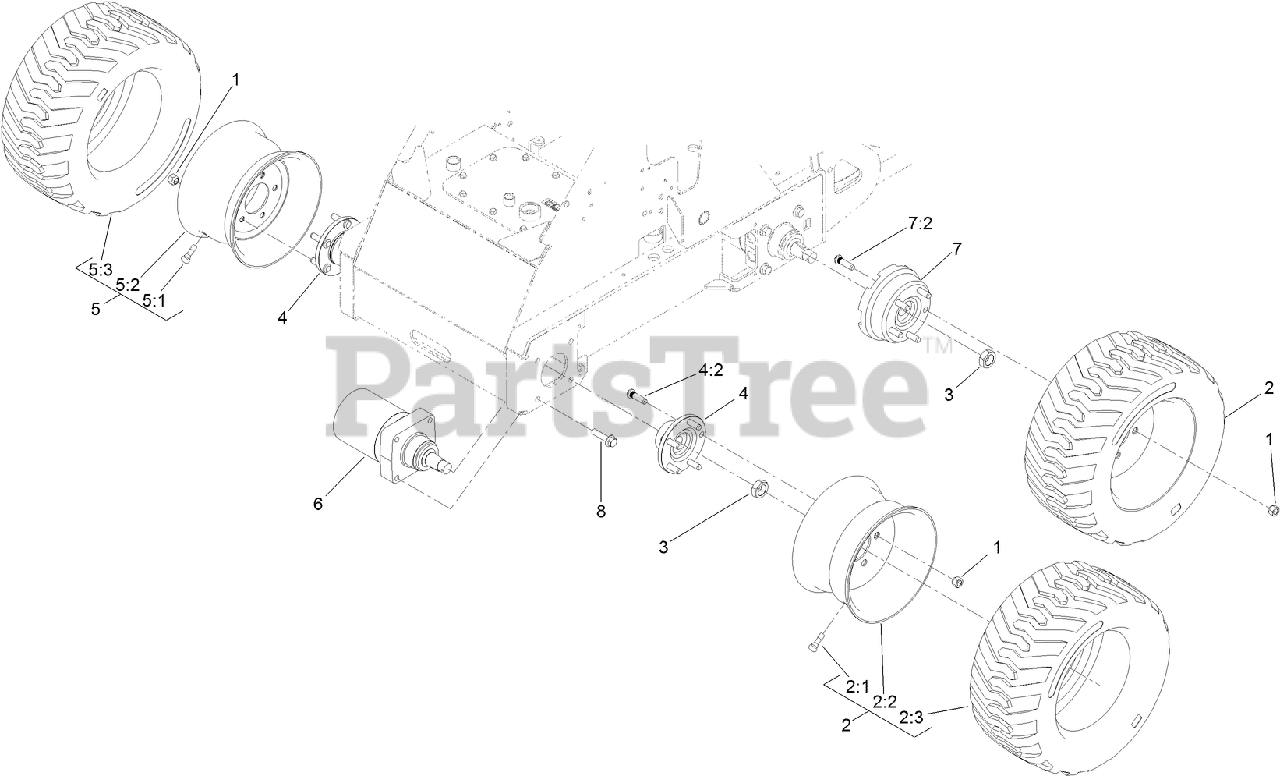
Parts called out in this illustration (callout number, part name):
1	NUT-LUG
2	LH WHEEL AND TIRE ASM
2:2	WHEEL
3	NUT-LOCK
4	HUB ASM
4:2	STUD-TYPE, DRIVE
5	RH WHEEL AND TIRE ASM
5:2	WHEEL
6	HYD MOTOR ASM
7	WHEEL HUB ASM
7:2	STUD-TYPE, DRIVE
8	SCREW-HHF
